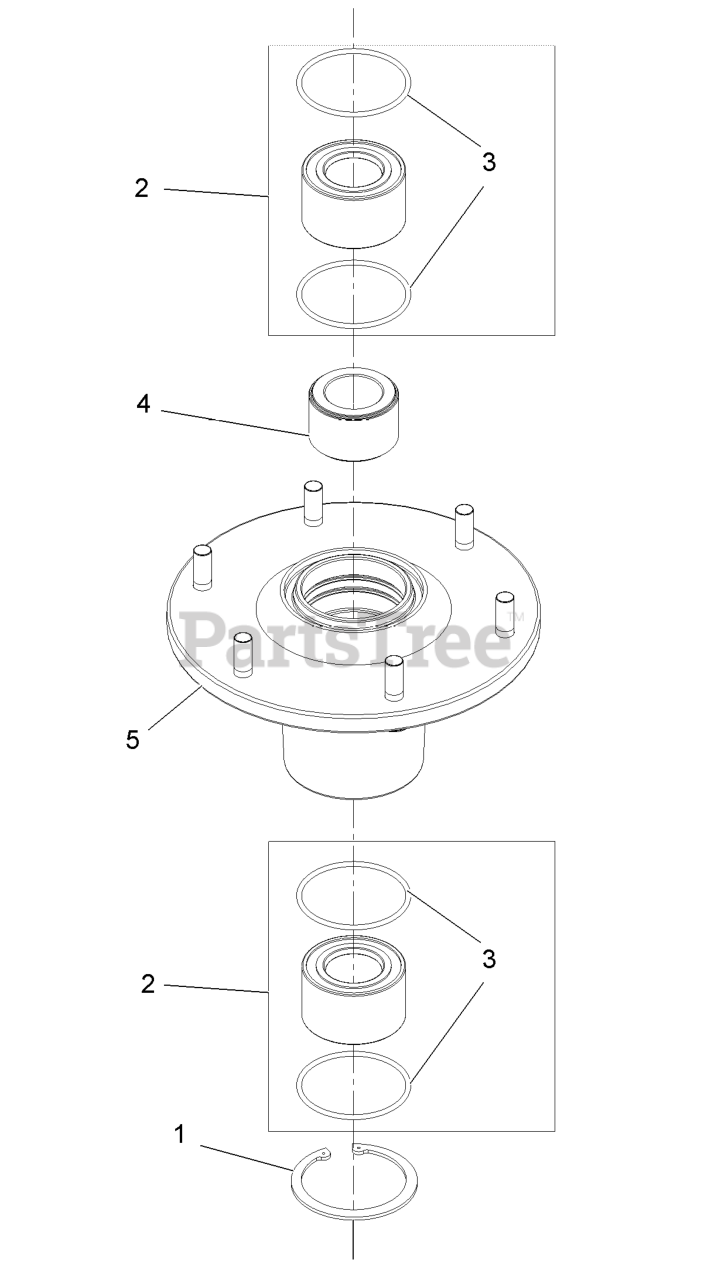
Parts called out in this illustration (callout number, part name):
1	RING-RETAINING
2	ASM, BEARING W/ORINGS
4	SPACER,BEARING
5	ASM,HOUSING W/STUDS
